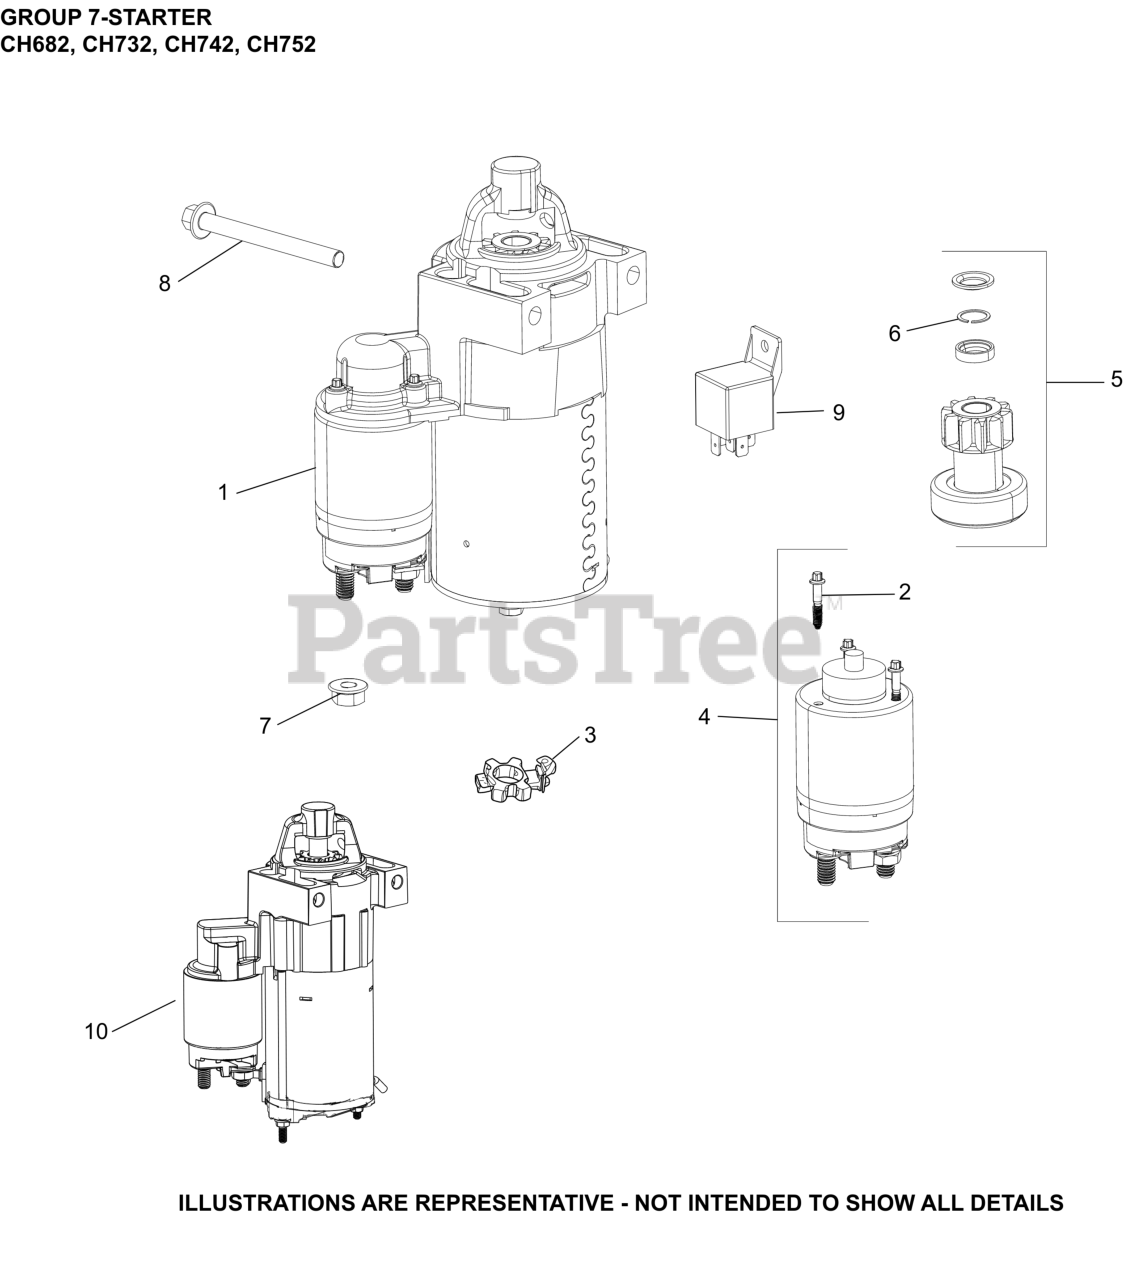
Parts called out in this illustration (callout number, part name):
7	NUT, FLG M8X1.25
8	SCREW, FLG M8X1.25X80
NI	STARTER, SOLENOID SHIFT
